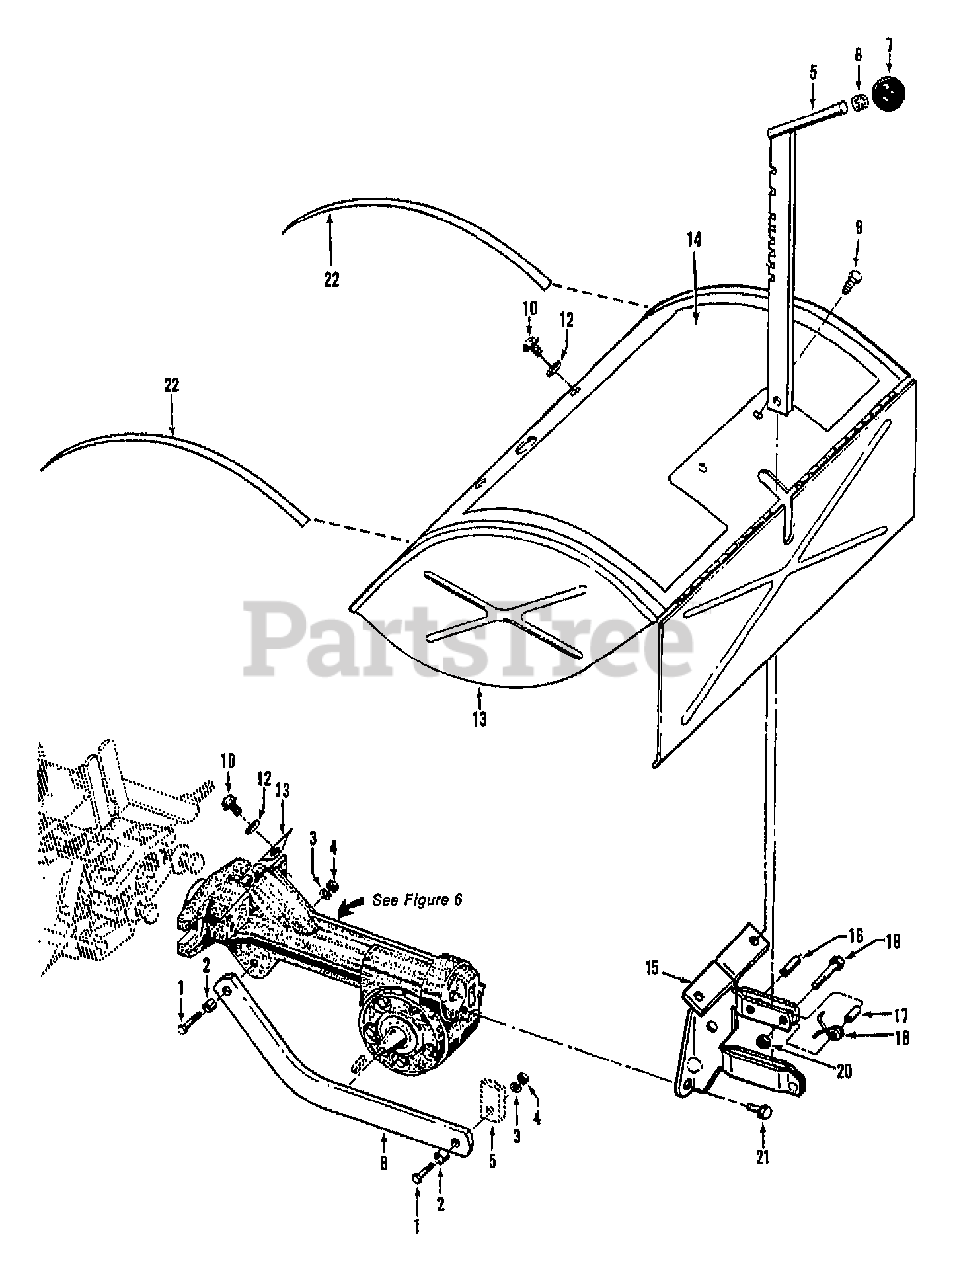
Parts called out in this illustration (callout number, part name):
1	SCR-HH 3/8-16X1.25
2	BUSHING-.5X.375X.3
3	WASHER-LK .375 @ DEPL
4	NUT-HEX 3/8-16 ZP
5	REGULATOR-DEPTH W/KNOB (INCL. #6 & #7)
6	RING-TOLERANCE .5325 ID
7	KNOB-CONTROL (INCL. #6)
8	BAR-DRAG BLACK
9	SCR-HWH 1/4-20 X .5 STH (LOCKWASHER & NUT NOT REQUIRED)
10	SCR-HFLK 5/16-18X.62 G5ZP
12	WASHER-#1.125X.344 ZP
13	HOOD-BLACK W/DECALS #14
14	DECAL-HOOD SPEC EDITION
15	BRKT-HOOD W/PIN #16
16	PIN-ROLL .25 X 1
17	SPACER-.250X.343X.375
18	SPRING-TORSION
19	SCR-HH 1/4-20X1.0
20	NUT-LK 1/4-20
21	SCR-HFLK 5/16-18X.62 G5ZP
22	DECAL-ACCENT HOOD
